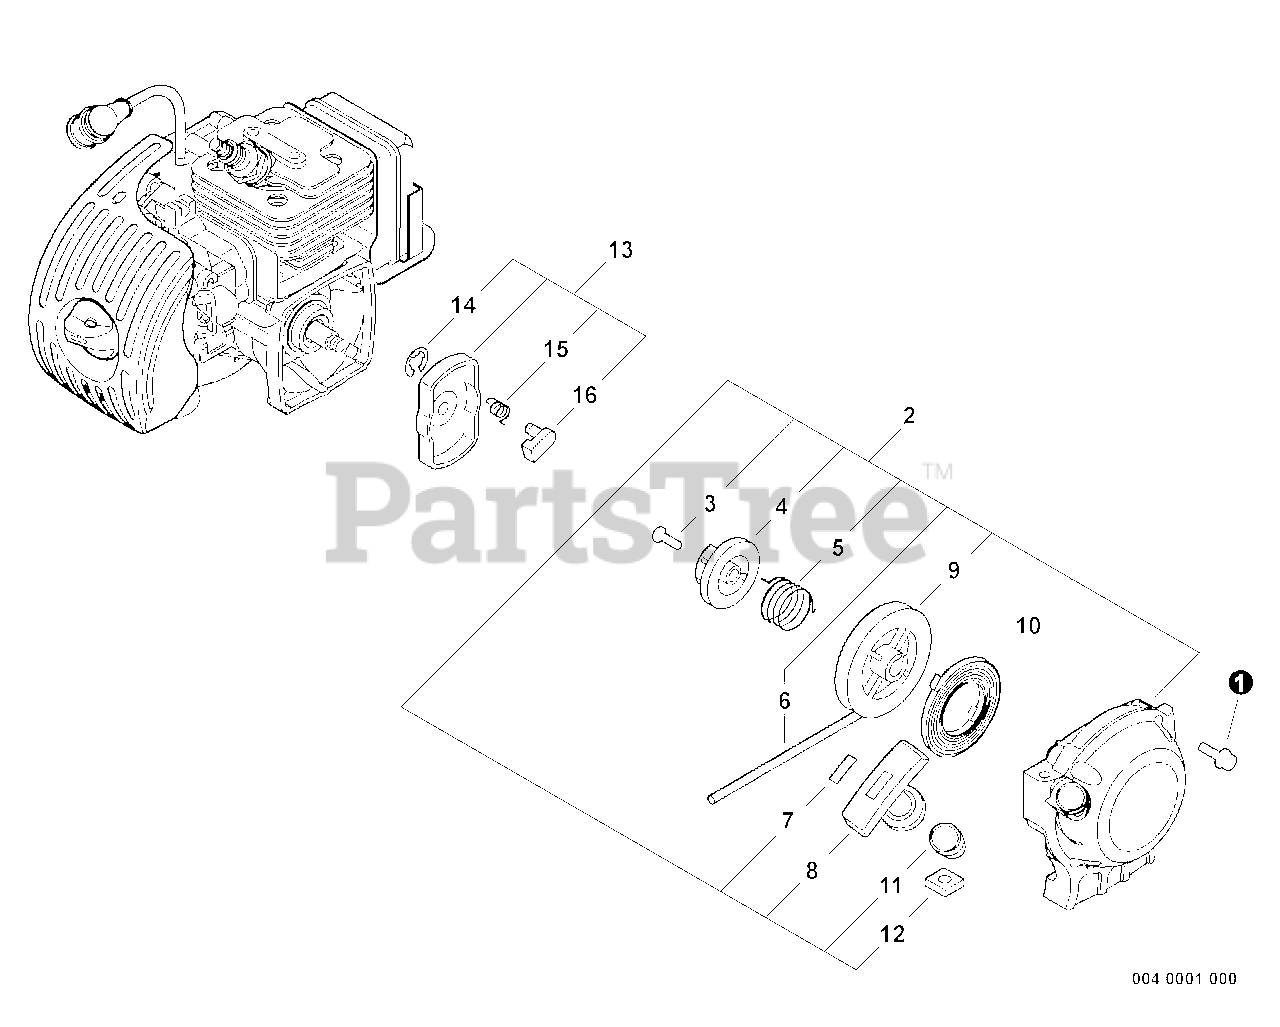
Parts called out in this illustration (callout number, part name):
1	SCREW - 4X16
2	STARTER ASSY
3	SCREW
4	PLATE, CAM
5	SPRING, DAMPER
6	ROPE, STARTER - 3X700
7	RETAINER, ROPE
8	GRIP, STARTER
9	REEL, ROPE
10	SPRING, REWIND
11	GUIDE, ROPE
12	NUT - 5 -- SQUARE
13	STARTER PAWL ASSY
14	RING, RETAINING - 4
15	SPRING, RETURN
16	PAWL, STARTER
